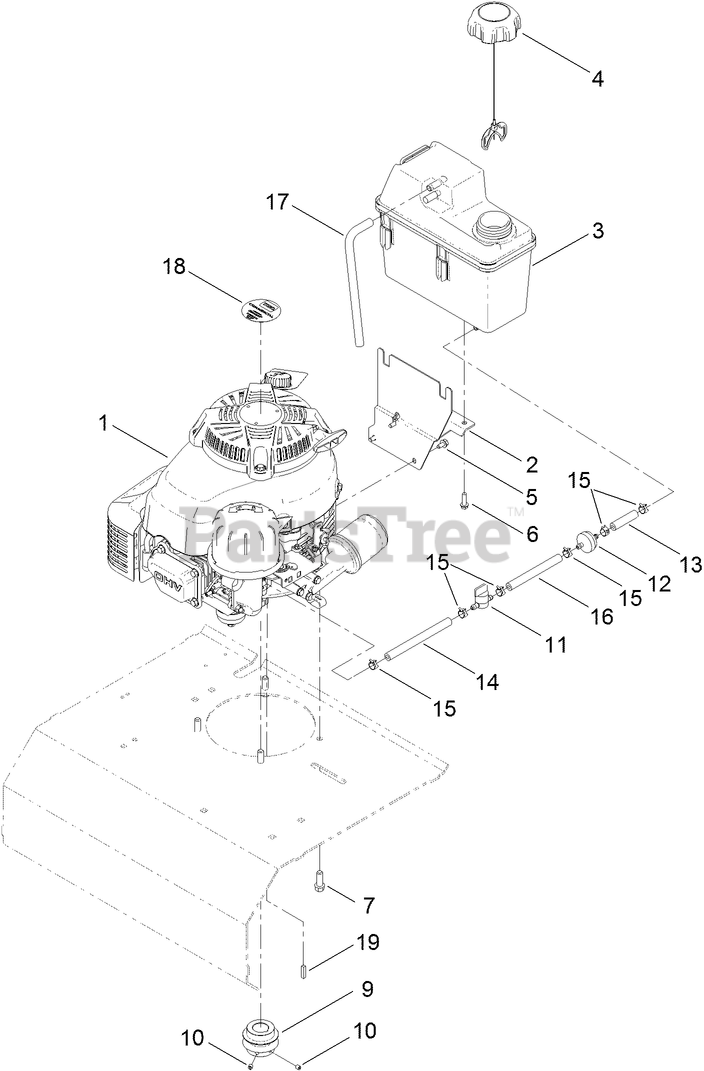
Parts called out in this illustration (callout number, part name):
2	MOUNT-TANK
3	TANK-FUEL
4	CAP-RATCHET, TETHERED
5	SCREW-HWH
6	SCREW-HWH
7	SCREW-TAPTITE
9	PULLEY-DRIVER
10	SCREW-SET, HSH
11	VALVE-FUEL
12	FILTER-FUEL
13	HOSE-FUEL
14	HOSE-FUEL
15	CLAMP-HOSE
16	HOSE-FUEL
17	HOSE-VENT, CANISTER
18	DECAL
19	KEY
